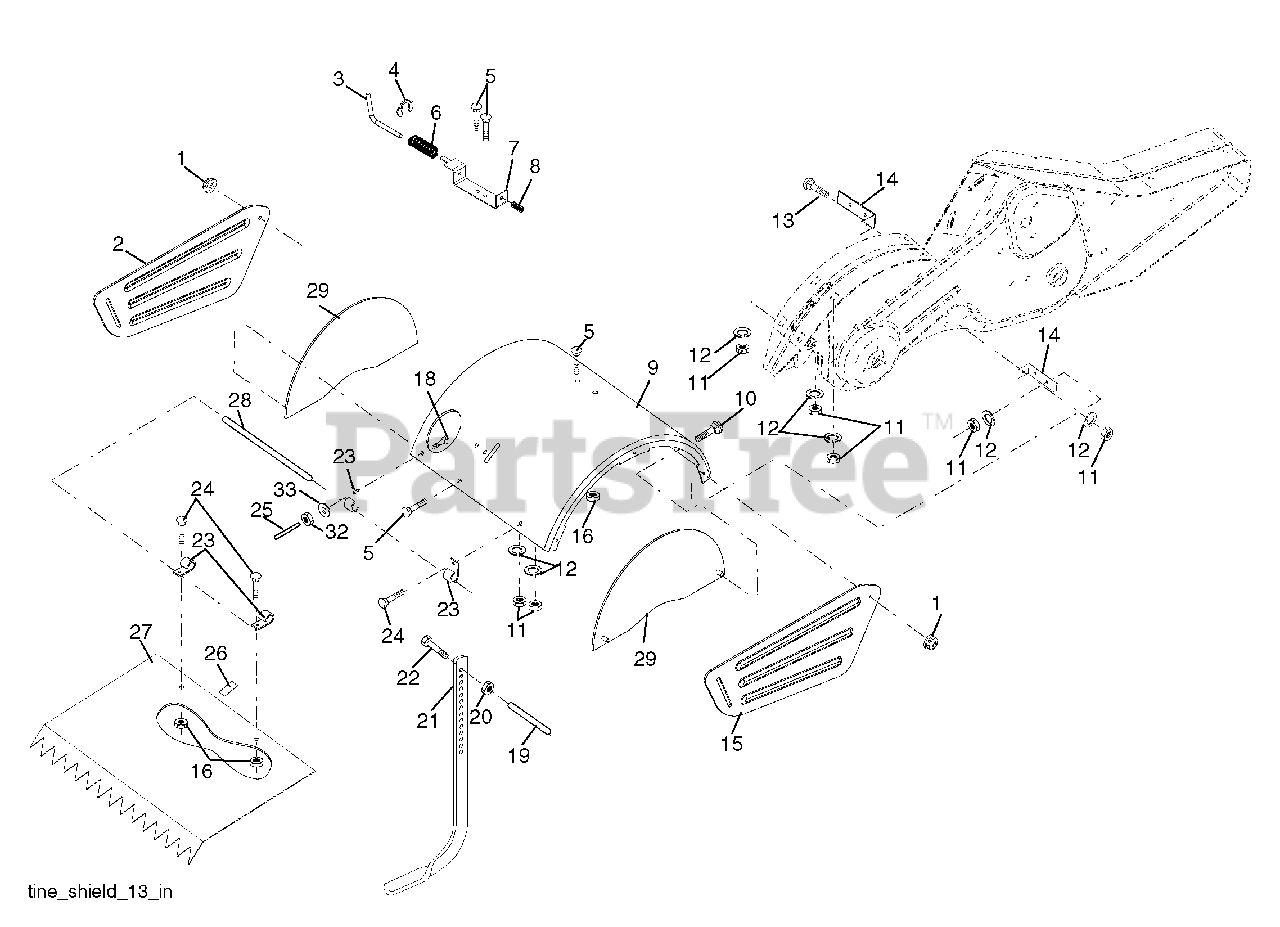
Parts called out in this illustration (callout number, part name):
1	Nut, Flange 5/16-18
2	Shield, Side, Outer L. H.
3	Pin, Stake, Depth
4	Ring, Klip
5	Bolt, Carriage 5/16-18 x 3/4
6	Spring
7	Bracket, Latch
8	Spring, Depth Stake
10	Bolt 5/16-18 x 1
11	Nut, Hex 5/16-18
12	Washer, Lock 5/16
13	Bolt, Carriage 5/16-18 x 1-1/4
14	Bracket, Shield Tine
15	Shield, Side, Outer R.H.
16	Nut, Hex Flange 1/4-20 unc
18	Bolt, Carriage 1/4-20 x 1-1/4 Gr. 5
19	Grip
20	Nut, Hex 3/8-16
21	Stake, Depth
22	Bolt, Hex 3/8-16 x 2
23	Hinge
24	Bolt, Carriage 1/4-20 x 1/2 Gr. 5
25	Cap, Vinyl
26	Pad, Idler
27	Shield, Leveling
28	Pin, Hinge
29	Shield, Side
32	Nut Fin Hex 1/4-20 unc
33	Washer Lock Hvy Helical 1/4
